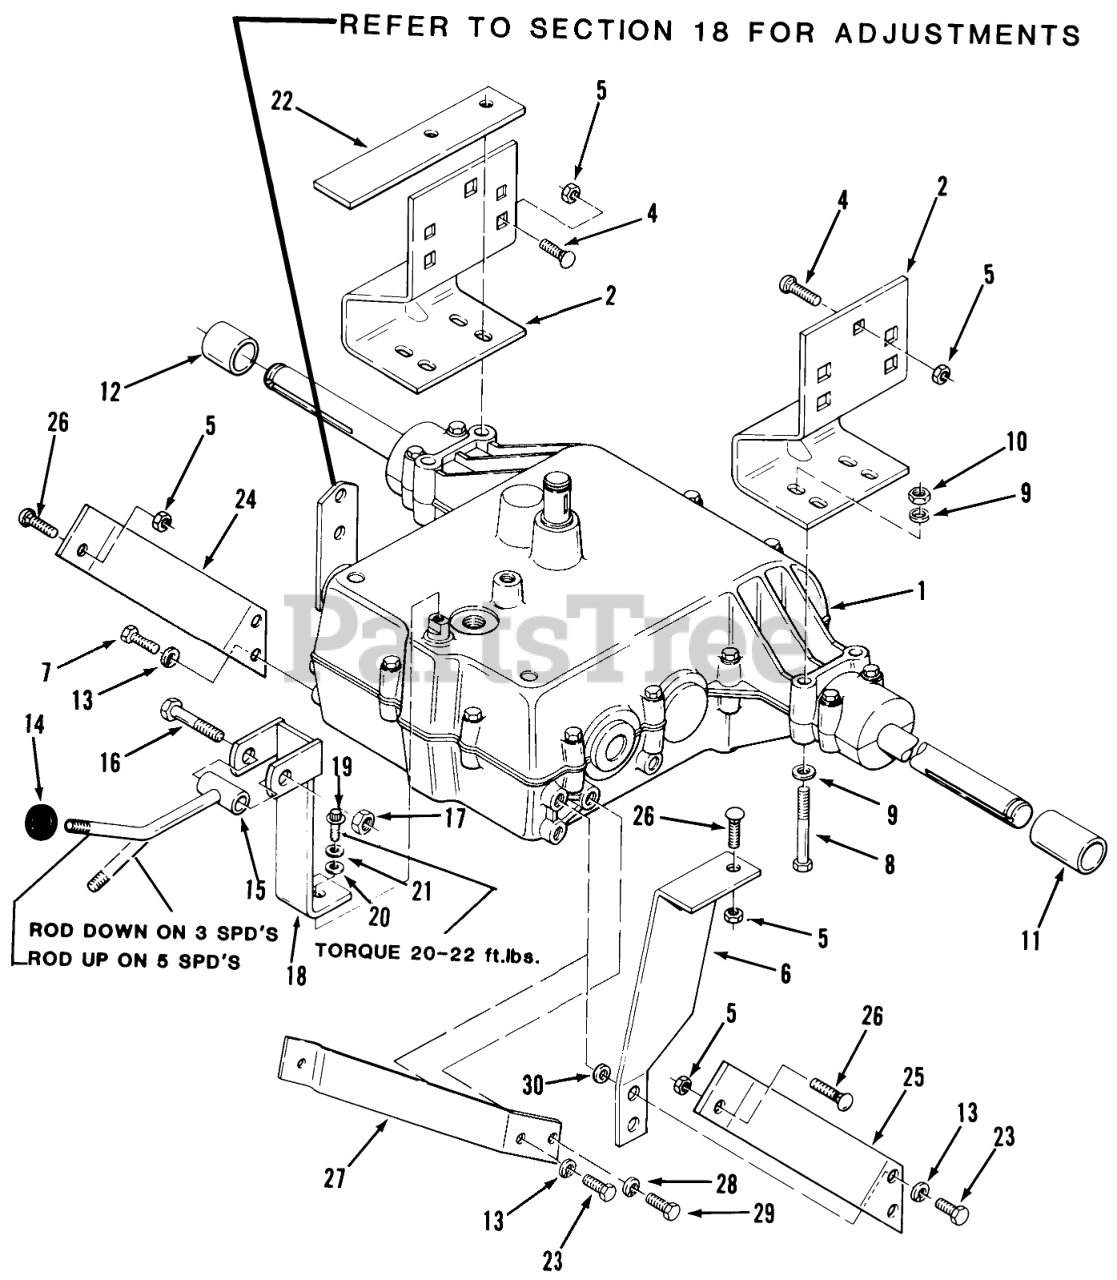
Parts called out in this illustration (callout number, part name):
1	Trans.-3-Spd.(Peerless Model 900-013)
2	Bracket-Rear Axle RH
4	Bolt
5	Nut
6	SPRING EXTENSION
7	Screw
8	HHCS
9	WASHER 5/16 SAE
10	Nut
11	SPACER
12	SPACER-AXLE RH
13	Lockwasher
15	ASSY UPPER SHIFT ROD
16	Bolt
17	Nut
18	Shift Lever-Lower 3-Speed Only
19	Bolt-12 Point-5-Speed
20	WASHER
21	WASHER SPECIAL
22	Brake Stop Bar 3-Speed Only
23	Bolt
24	TORQUE STRAP RH R
25	Torque Strap LH 211-5 Only
26	Bolt
27	TORQUE STRAP LH R
28	Washer
29	Bolt, 1/4-20 x 3/4 Swage Form
